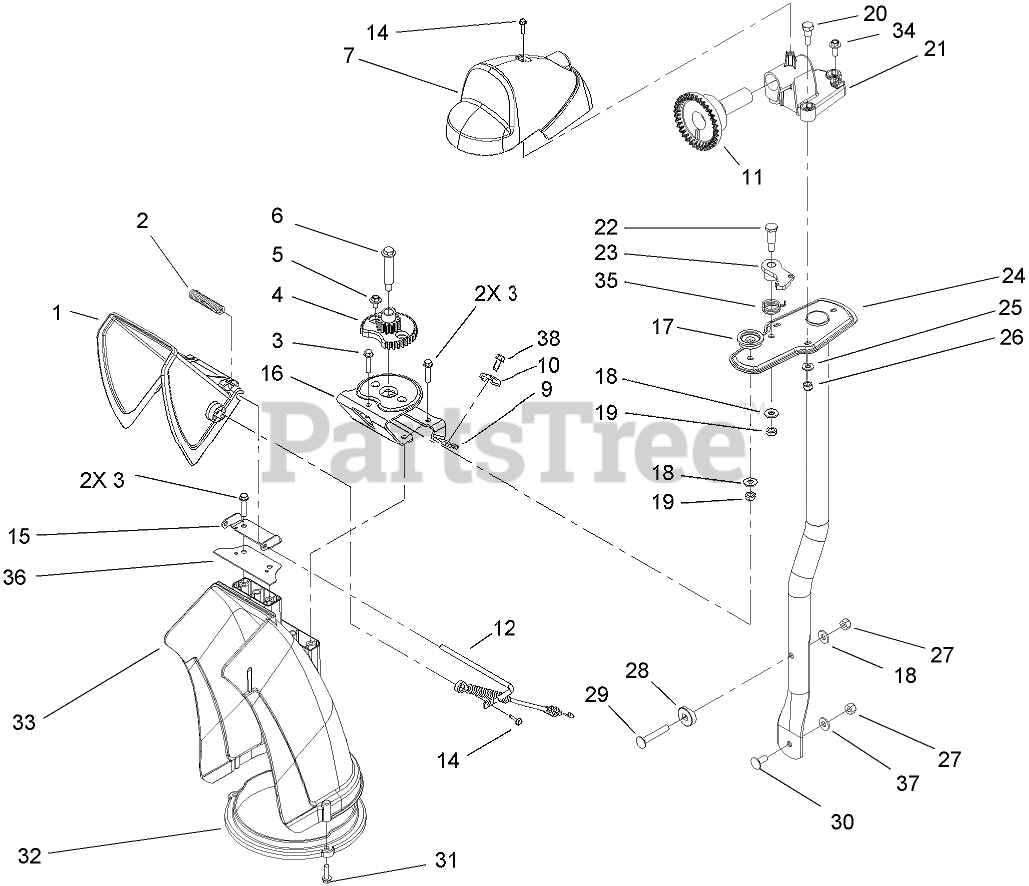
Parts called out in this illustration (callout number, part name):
1	DEFLECTOR-CHUTE
2	SPRING-TORSION
3	SCREW-PLASTITE
4	GEAR-CHUTE
5	SCREW AND WASHER ASM
6	BOLT-SHOULDER
7	COVER-GEAR, CHUTE
9	BRACKET-CABLE, CLAMP
10	CLAMP-CABLE
11	GEAR-FACE
12	ROD-DEFLECTOR
14	SCREW-HWH
15	BRACKET-DEFLECTOR
16	BRACKET-SUPPORT, CHUTE
17	SPACER-CHUTE
18	WASHER-FLAT
19	NUT-LOCK, NI
20	SCREW-SHOULDER
21	MOUNT-GEAR, FACE
22	SCREW-SHOULDER
23	LATCH-CHUTE
24	TUBE-SUPPORT
25	WASHER-FLAT
26	NUT-LOCK, NI
27	NUT-LOCK, NI
28	WASHER-CURVED
29	SCREW-CARR
30	SCREW-CARR
31	SCREW-HWH
32	RING-CHUTE
33	CHUTE-DISCHARGE
34	SCREW-HWH
35	SPRING-TORSION
36	SEAL-CHUTE
37	WASHER-BELLEVILLE
38	SCREW-HWH
